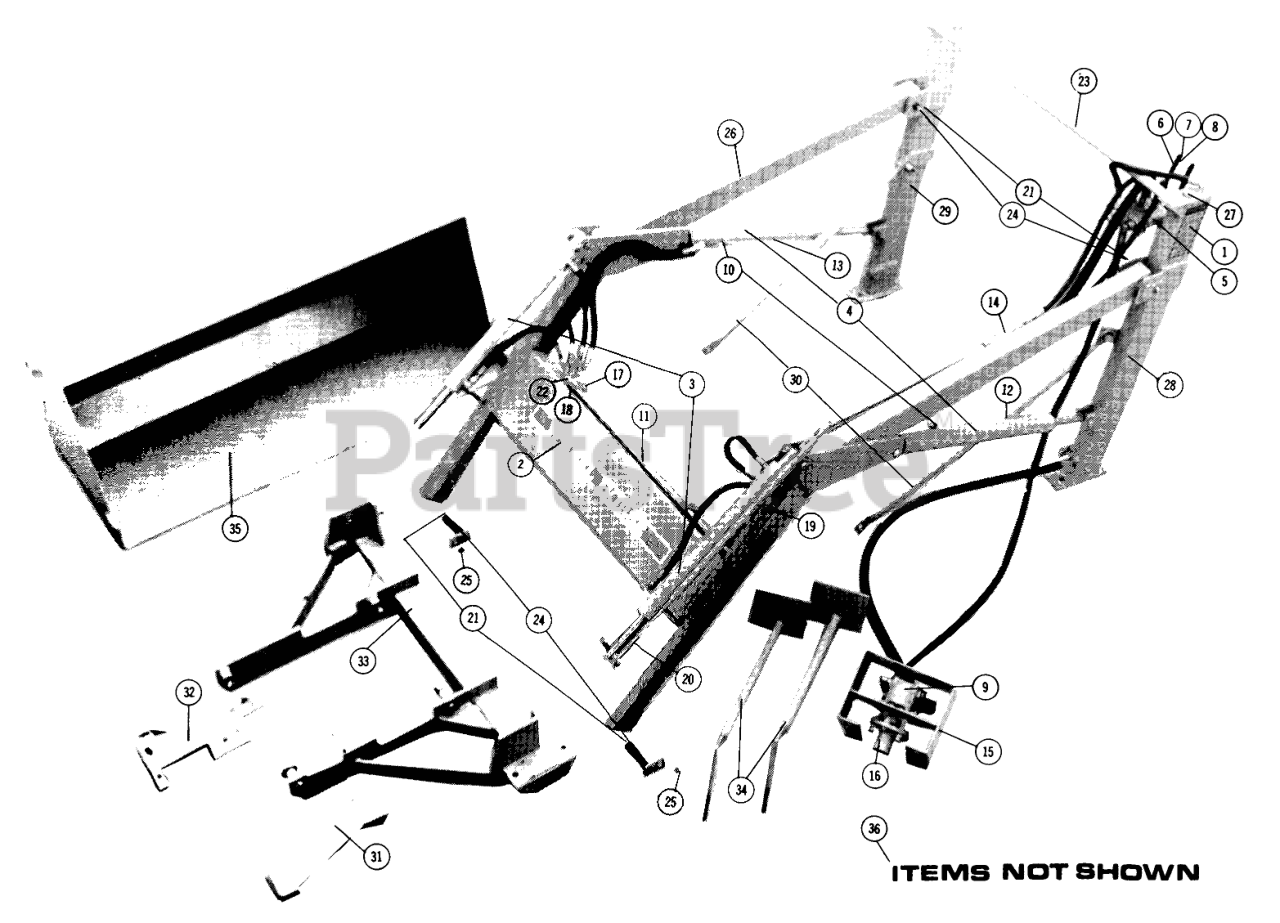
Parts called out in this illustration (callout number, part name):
1	Decal, Caution
2	Decal, Wheel Horse
3	Tilt Cylinder
4	Lift Cylinder
5	Control VaIve
6	Handle Linkage
7	Black Vinyl Cover
8	Valve Handle (with Cover)
9	Hydraulic Pump
10	52014/15/90A RER 34
11	Self Tapping Screw
12	Hydraulic Cylinder Tube LH
13	Hydraulic Cylinder Tube RH
14	Hydraulic Line
15	Pump Mounting Bracket
16	Pump Coupling
17	Hydraulic Line Hold Down
18	Hydraulic Line Bracket
19	Bucket Guide Tube
20	Bucket Guide Rod
21	Grease Fitting
22	Foam Cushion
23	Stabilizer Bar
24	Lift Frame Pin
25	Lift Frame Pin Bushing
26	Lift Frame Assembly
27	Breather Cap
28	Left Upright
29	Right Upright
30	Brace Arm
31	Front Mounting Bracket (Left)
32	Front Mounting Bracket (Right)
33	Underframe Assembly
34	Dismount Stand
35	48 in. (122 cm) Heavy Duty Bucket
36	Ballast Box
36	Upper Link (3-Point Hitch)
